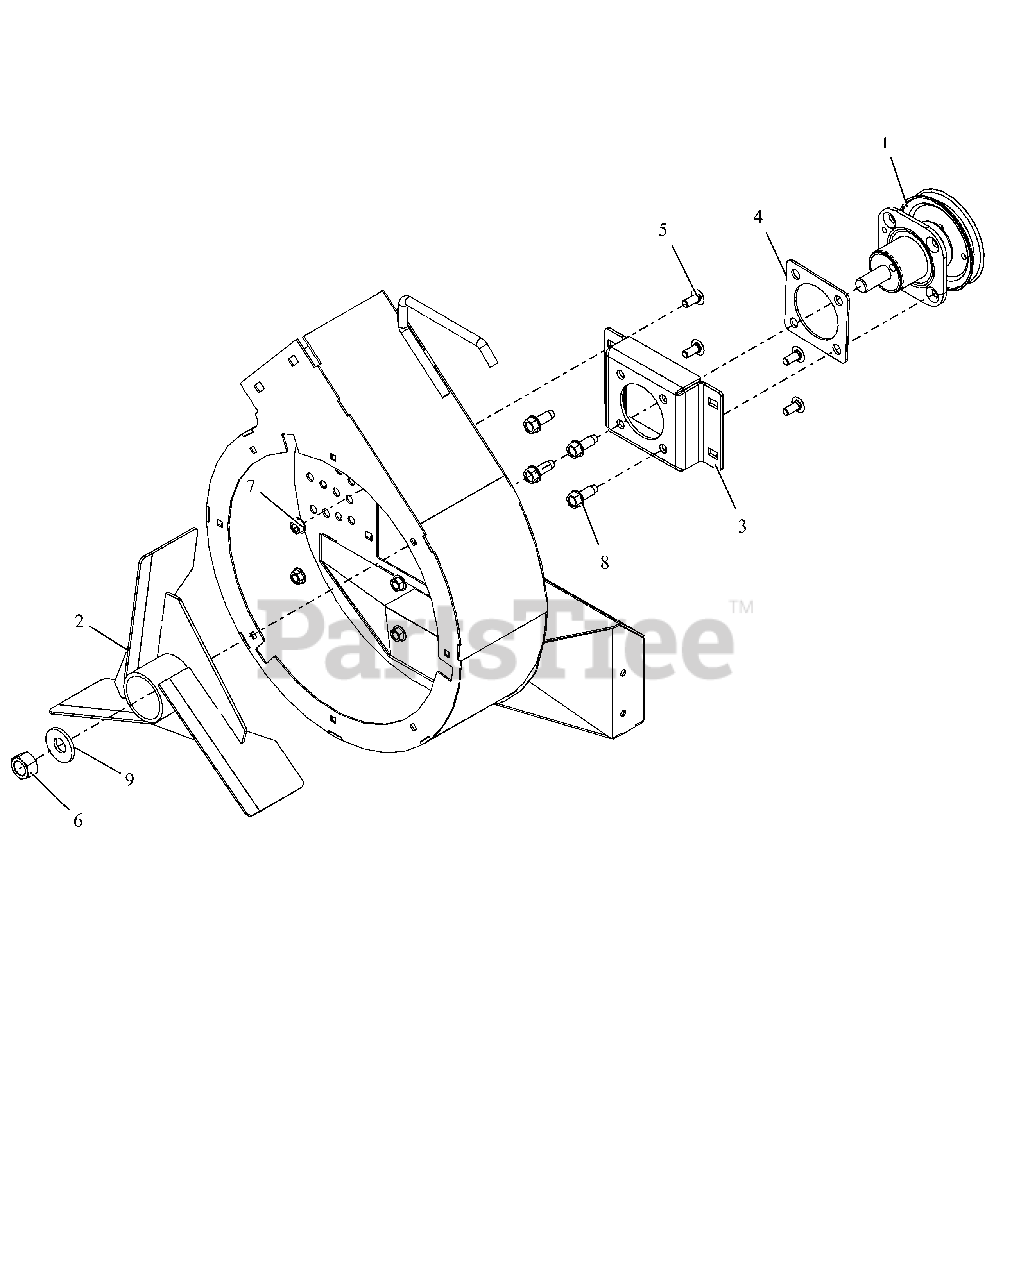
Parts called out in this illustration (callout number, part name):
1	KIT, DECK SPINDLE ASM (42)
2	WLDMT, FAN (BLOWER)
3	MOUNT, SPINDLE STANDOFF
4	SPACER, BAGGER SPINDLE
5	@BLT-RHDSSQNK .31-18X.75 G5YZ
6	NUT-HEX .62-18 YWZC
7	@NUT-LK-TOP-FLG .31-18 YWZC
8	@SCR-TAP .38-16X1.00 HWH TR YZ
9	WSHR-BLVL .669X1.535X.138
